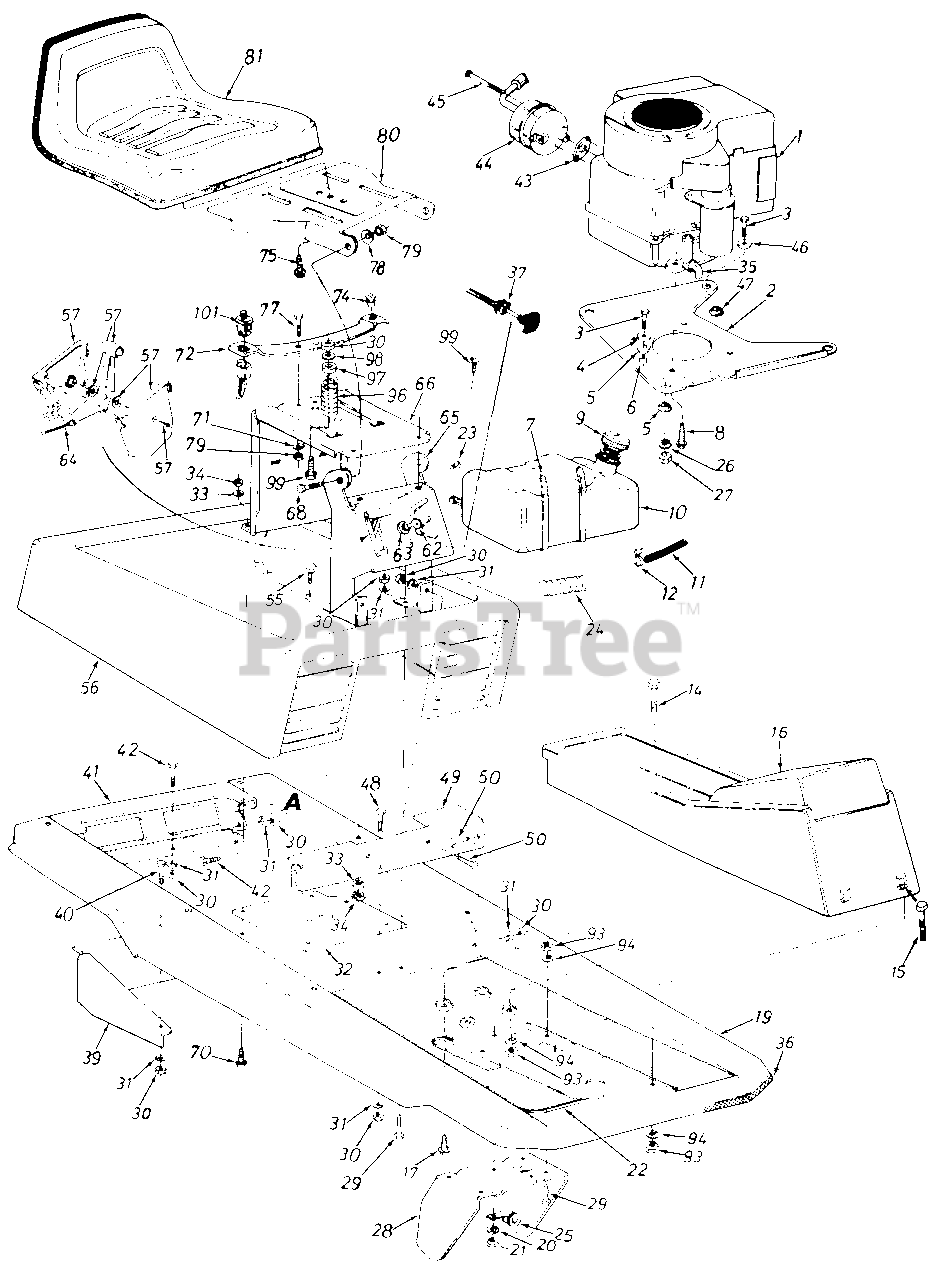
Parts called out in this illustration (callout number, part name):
1	Engine
4	Fl-Wash. .330" l.D. x 1.125" O.D.
5	Engine Mounting Grommet
6	Spacer.315" I.D. x .50" O.D. x.520" Lg.
7	Cable Tie 30.6" Lg.
8	Hex Wash. Hd. Self-Tap Scr. 3/8-16 x 1.25" Lg.
10	Fuel Tank
11	Gas Line-26 Inches
12	Hose Clamp 1/2" O.D. Tube
14	Hex Bolt 5/16-18 x 1.75" Lg.
15	Hex Bolt 5/16-18 x 2.0" Lg.
16	Front Console
17	Plastite Scr. 5/16 x 1.25" Lg.
19	483/N Main Frame
20	L-Wash. 5/16" I.D.
21	Hex Nut 5/16-18 Thd.
23	Truss Mach. AB-Tap Scr. #10 x .50" Lg.
24	Convoluted Conduit
26	L-Wash. 5/16" I.D.t
27	Hex Nut 5/16-24 Thd.
28	Clutch-Brake Pedal Ass'y.
29	Hex Bolt 5/16-18 x .75" Lg
30	Hex Nut 5/16-18 Thd.
31	L-Wash. 5/16" I.D.
32	Mounting Brkt. Variable Speed Pulley
33	L-Wash. 1/4" I.D.
34	Hex Nut 1/4-20 Thd.
35	90ø Elbow Male To Female
36	Trim Strip 18" Lg.
37	Choke Control
43	Exhaust Gasket
44	Muffler Ass'y.
45	Shld. Bolt
46	Fl-Wash. .33" I.D. x 1.25" O.D.
47	Flange Wash. .32" I.D. x 75" O.D.
48	Hex Bolt 5/16-18 x .75" Lg.
49	Seat Support & Frame Brkt.
50	Hex Bolt 5/16-18 x 75" Lg.
55	Hex Bolt 1/4-20 x 50" Lg.
56	Engine Cover Ass'y.
57	Throttle Control Box Ass'y.
62	Ignition Key
63	Ignition Switch
64	Throttle Control Wire
70	Hex Tap Scr. 1/4-20 x 1.0" Lg.*
71	L-Wash. 5/16" I.D.
75	Hex Wash. Hd. Tap Scr. 3/8-16 x 3/4" Lg.
77	Hex Bolt 5/16-18 x .75" Lg.
78	Bell-Wash. 34Sn l.D. x .88" O.D.
79	Hex Cent. L-Nut 5/16-18 Thd.
80	Seat Pivot Bracket
81	Seat Ass'y.
93	Hex Nut 5/16-18 Thd.
94	L-Wash. 5/16" l.D.
96	Compression Spring 2.61" Lg.
98	Fl-Wash. 344" l.D. x .875"
99	Hex Bolt 5/16-18 x l" Lg. (Gr. S)
